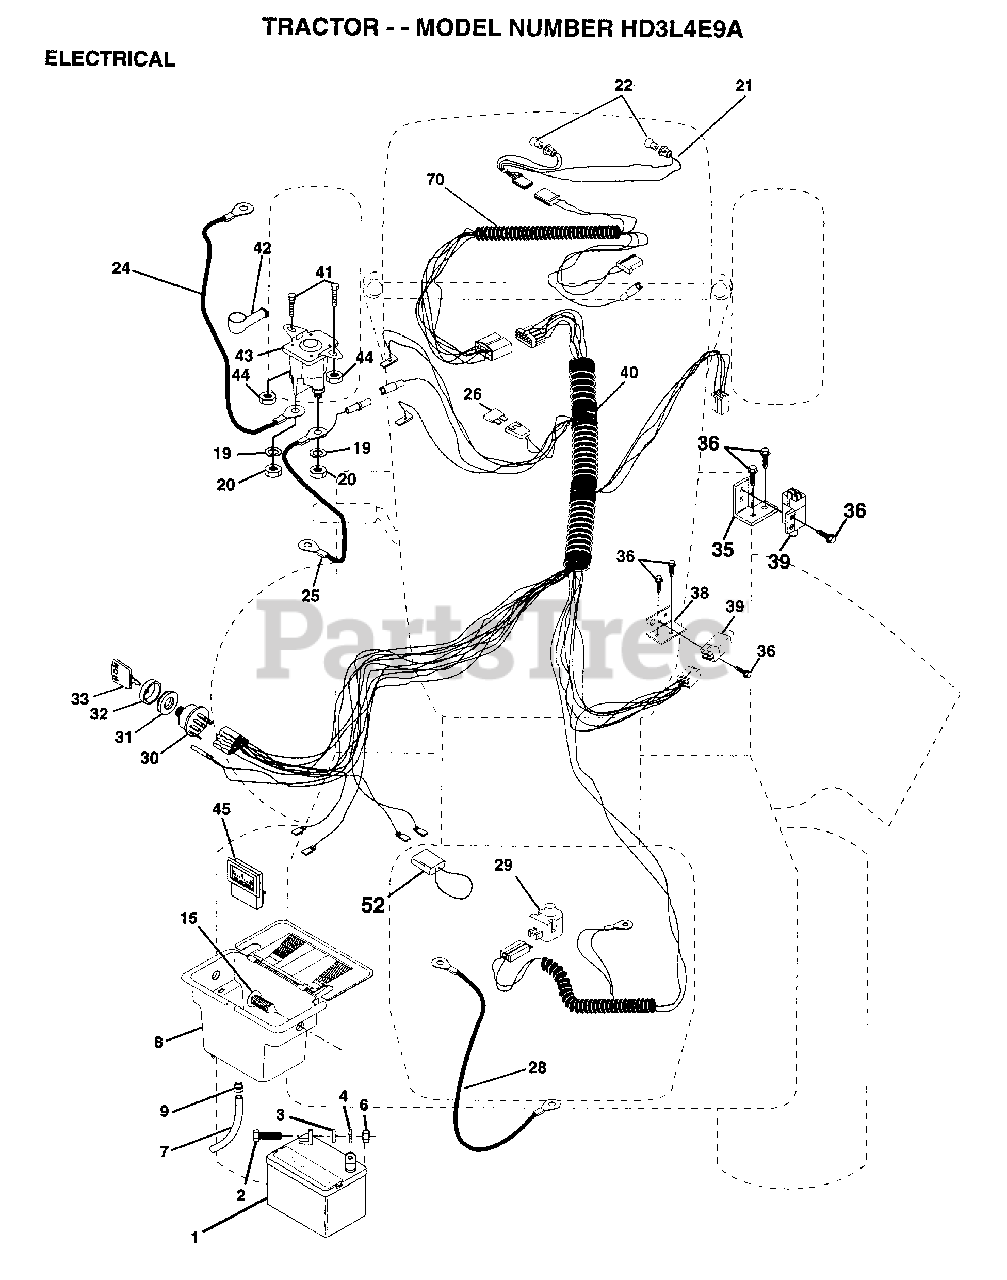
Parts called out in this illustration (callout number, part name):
2	BOLT LT
3	WASHER
4	LOCKWASHER
7	TUBE T
9	HOSE CLAMP T
15	FASTNER.SNAP-IN
20	NUT
21	"HARNESS,LIGHT SOC"
22	HEADLAMP BULB
24	CABLE-BATTERY T
25	CABLE.BTRY.6GA.RD
26	FUSE HYT
28	CABLE T
29	SWITCH SEAT
30	SWITCH IGN 4POS
31	NUT IGNITION
32	COVER KEY SWITCH
33	KEY
35	BRACKET LT
36	SCREW
38	BRACKET SWITCH IN
39	SWITCH INTERLOCKT
40	HARNESS.IGNITION
41	BOLT HXHD FIN
44	NUT HXKEP 1/4X20
52	PROTECTION LOOP
70	HARNESS.ENG.LT.
